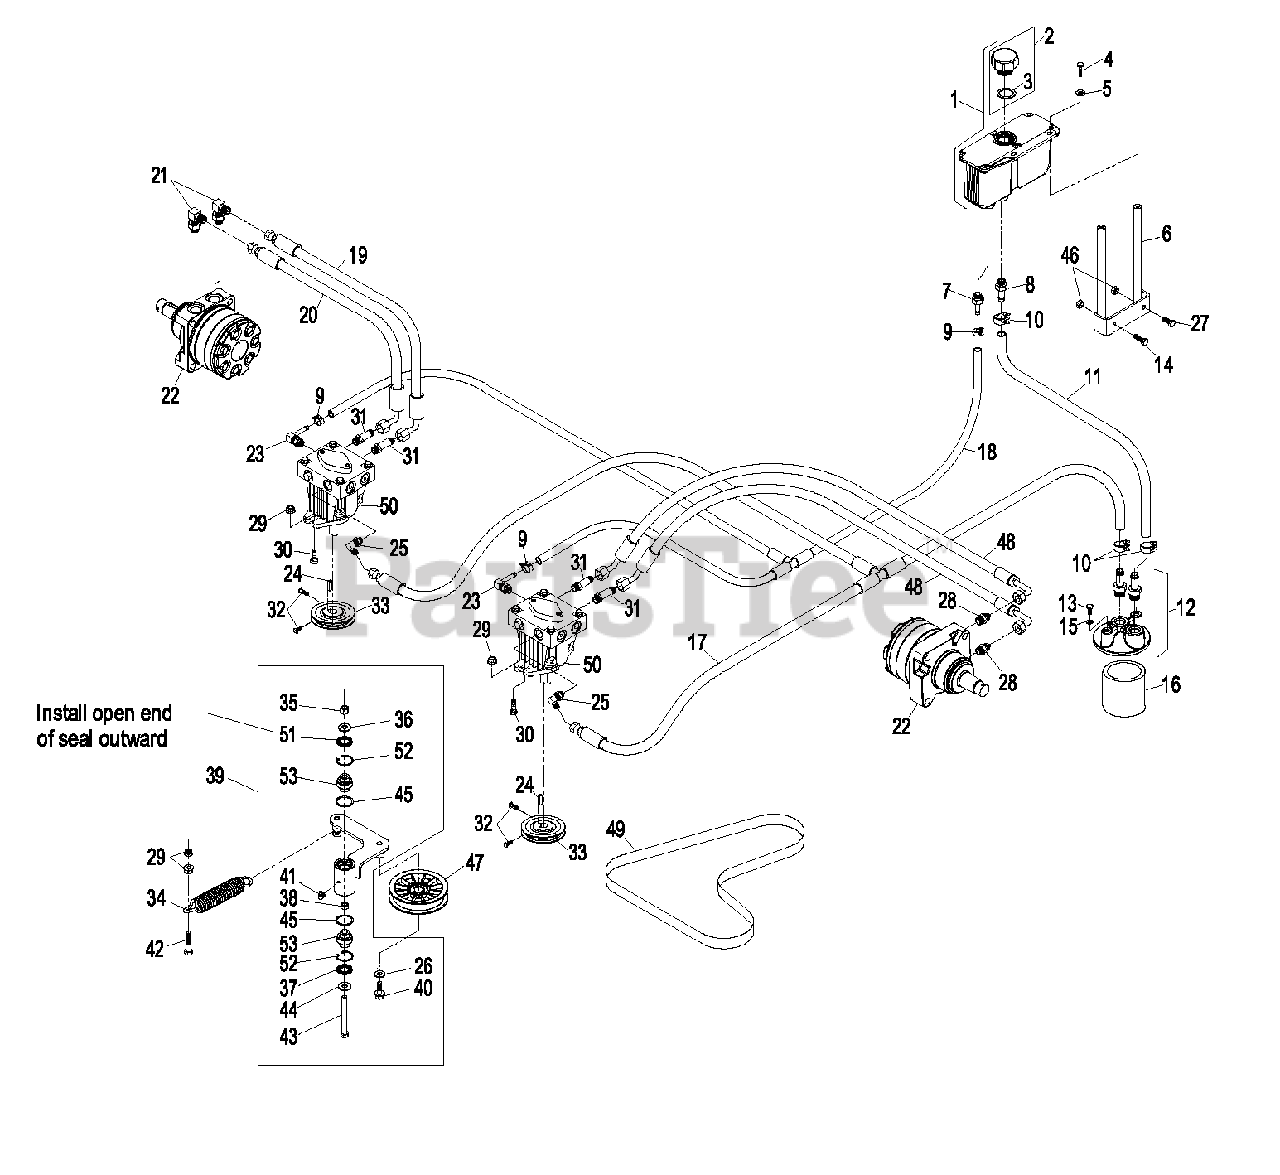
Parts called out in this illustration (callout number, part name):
1	HYD RESERVOIR ASM
2	KIT,HYD RES CAP W/GASKET
3	GASKET-CAP
4	SCREW-HH
5	WASHER-FLAT
6	STAND-RESERVOIR
7	ADAPTER-STRAIGHT
8	ADAPTER-STRAIGHT
9	CLAMP-HOSE
10	CLAMP-HOSE
11	HYD HOSE ASM
12	FILTER HEAD ASM
12	ADAPTER-STRAIGHT
13	SCREW-HH
14	SCREW-HH
15	WASHER-LOCK
16	FILTER-25 MICRON, BI-DIRE
16	ELEMENT-FILTER, WINTER
17	HYD HOSE ASM
18	HYD HOSE ASM
19	HOSE-REAR, RH
19	HOSE,HYDRAULIC
20	HOSE,RH FRONT 46/50
20	HOSE,RH FRONT 56
21	FITTING-HYD, 90 DEG
22	KIT, OUTPUT SHAFT & SEALS
22	MOTOR-WHEEL
22	OUTPUT SHAFT AND SEALS KI
22	SEAL KIT
23	ELBOW-90 DEG
25	FITTING-ELBOW, 90 DEG
26	WASHER-FLAT
27	SCREW-HH
28	FITTING-STRAIGHT
29	NUT-HHF, WHIZ
30	SCREW-HH
31	ADAPTER-STR, LONG
32	SCREW-SET
35	NUT-LOCK, NI
36	WASHER-BELLEVILLE
37	SEAL-LIP, DOUBLE
39	KIT, PUMP IDLER LHP/LCT
40	SCREW-HHF
41	FITTING-GREASE, 90 DEG
42	SCREW-HH
43	SCREW-HH
44	WASHER-FLAT
47	PULLEY-IDLER, FLAT
48	HOSE,LH 46/50
48	HOSE,LH 56
49	BELT
50	PUMP-HYD
50	INPUT SHAFT KIT
50	BEARING-THRUST
50	CYLINDER BLOCK KIT
50	SEAL OVERHAUL KIT
50	SHOCK VALVE KIT
51	SEAL-LIP, SINGLE
52	RING-SNAP
53	BEARING-SPHERICAL
